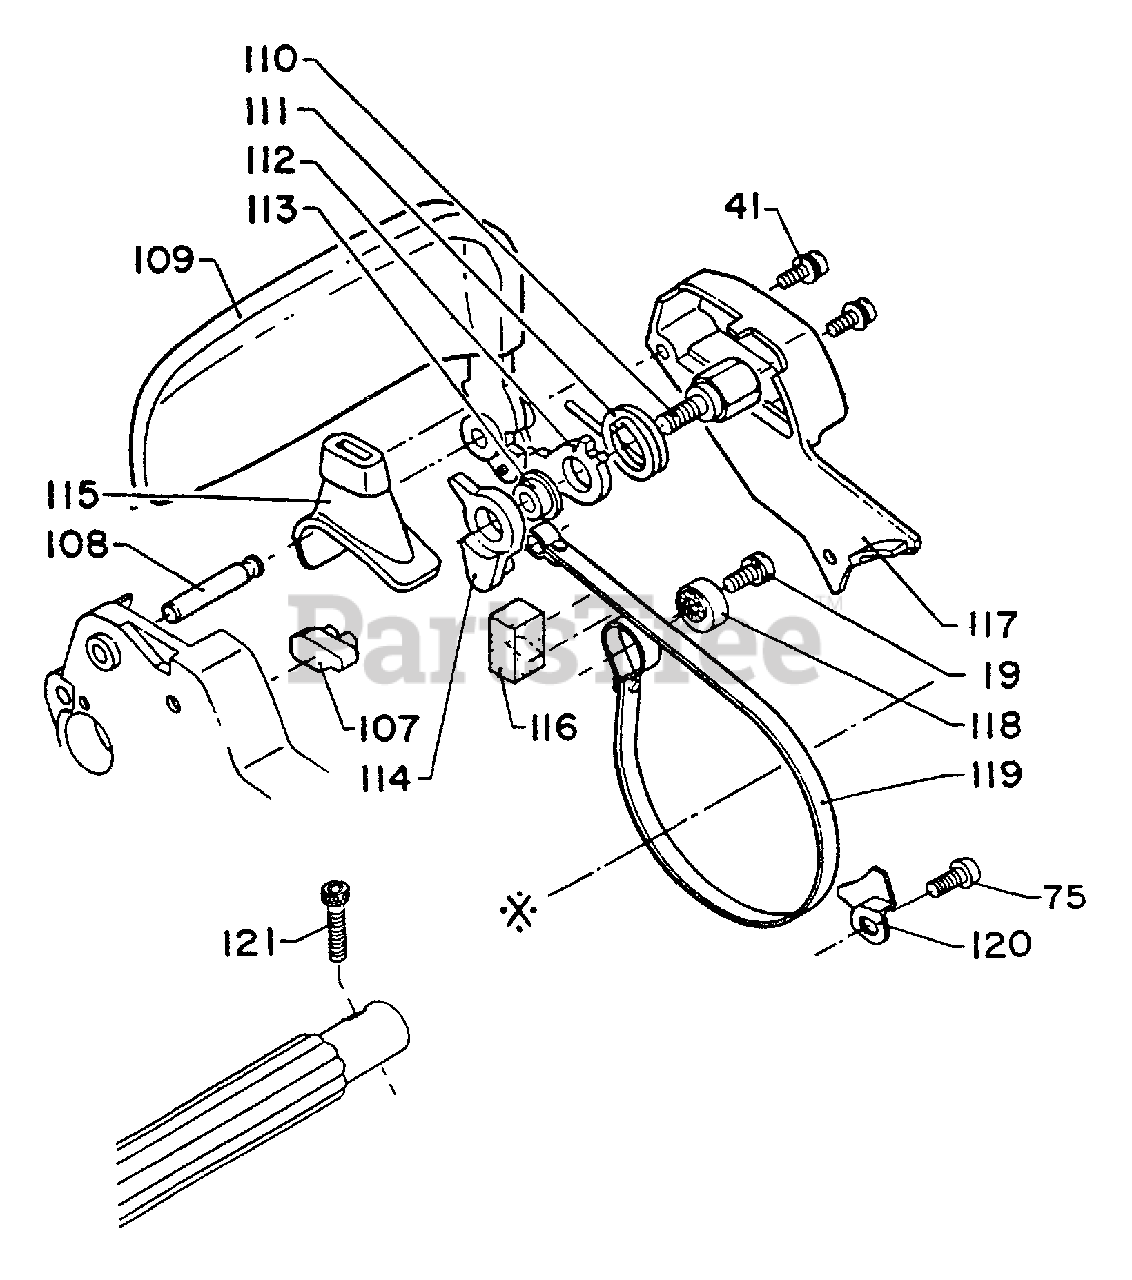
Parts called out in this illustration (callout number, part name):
19	SCREW - 5X10
41	SCREW - 4X10
75	SCREW - 5X10
107	RESET, BRAKE
109	HANDLE, BRAKE
111	SPRING, RETURN
114	CONNECTOR
115	COVER, BRAKE
116	SEAL
117	COVER, BRAKE
118	ADJUSTER, BRAKE BAND
119	BAND, BRAKE
120	RETAINER, BRAKE BAND
121	SCREW - 5X25
